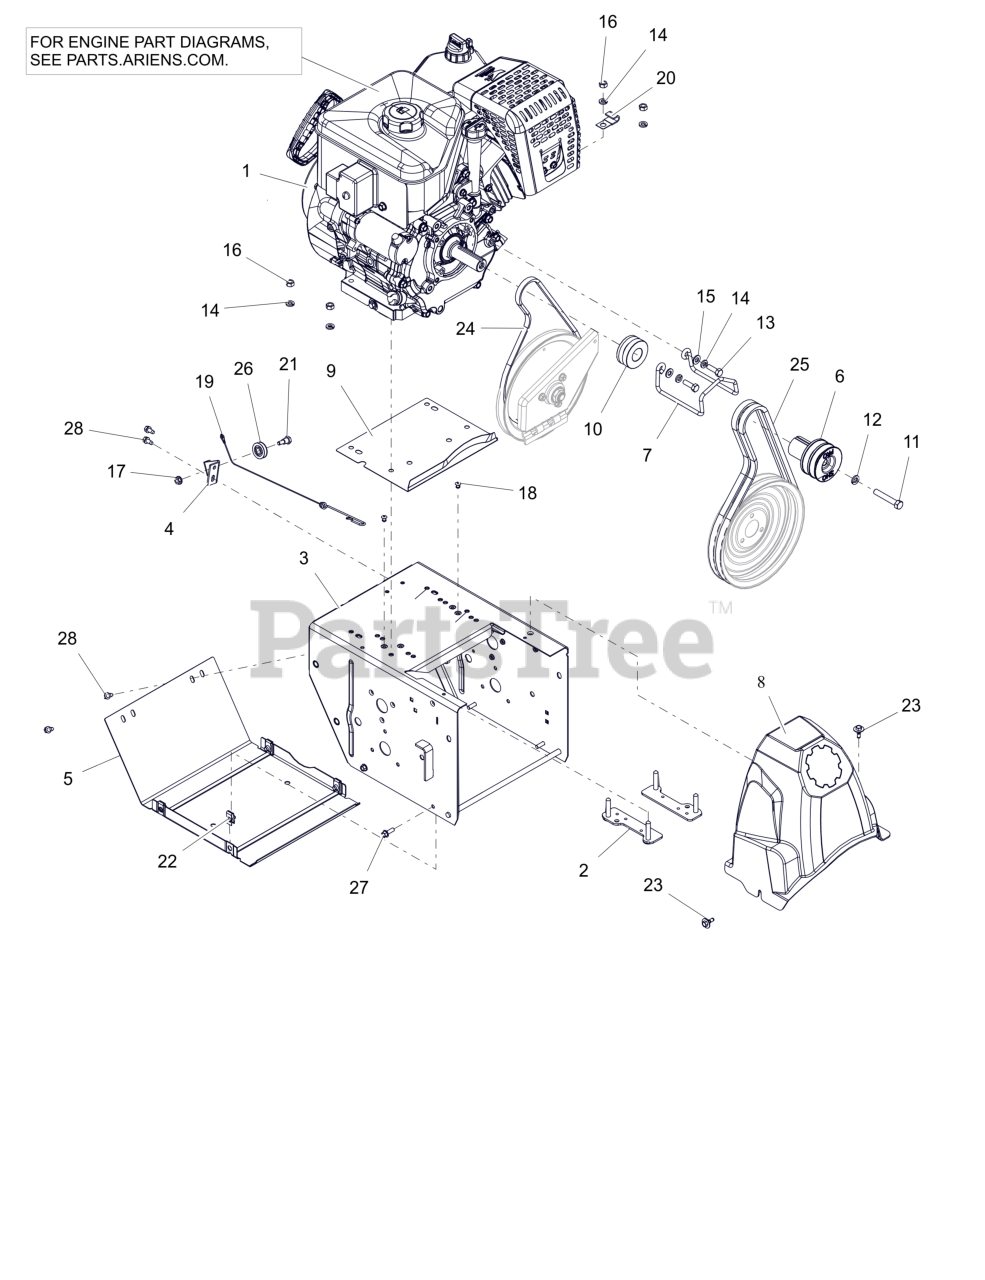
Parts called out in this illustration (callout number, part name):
1	ENGINE, AX369 GEN3 120V/60W
2	STRAP, BOLT-LARGE
3	FRAME, MAIN - 14GA DELUXE (ORANGE)
4	BRACKET, CABLE PULLEY
5	COVER, BOTTOM
6	SHEAVE,ATTACHMENT-SHO 2 GRV
7	FINGER, BELT
8	COVER, BELT
9	BAFFLE, WATER - LARGE BLOCK
10	SHEAVE, TRACTION (KEYLESS)
11	BLT, HEX .38-24X2.25 G5 ZCC
12	WSHR,LK-REG .375X.094 ZCC
13	BLT, HEX 0.3125-24X1 G5 ZCC
14	WSHR, LK-HVY .312X.097 ZCC
15	WSHR,FLT .344X.688X.065 ZCC
16	NUT, HEX .312-18 ZCC
17	NUT-LK-TOP-FLG .250-20 GF ZCC
18	RVT, POP .1875 ZCC
19	CABLE, LOWER TRACTION,SS & PRO
20	J-CLAMP
21	BOLT, SHLDR -.375 X .375 X .25-20
22	NUT-RTNR .25-20X.56
23	SCR-TAP .25-20X.5 CAPTIVE
24	V-BELT, 3L-WRAPPED
25	V-BELT, HA-RAW EDGE (SET)
26	PULLEY, CABLE
27	BLT, HWH .25-20X.75 G5 ZCC
28	SCR-TAP .25-20X.50 HWH ZCC
